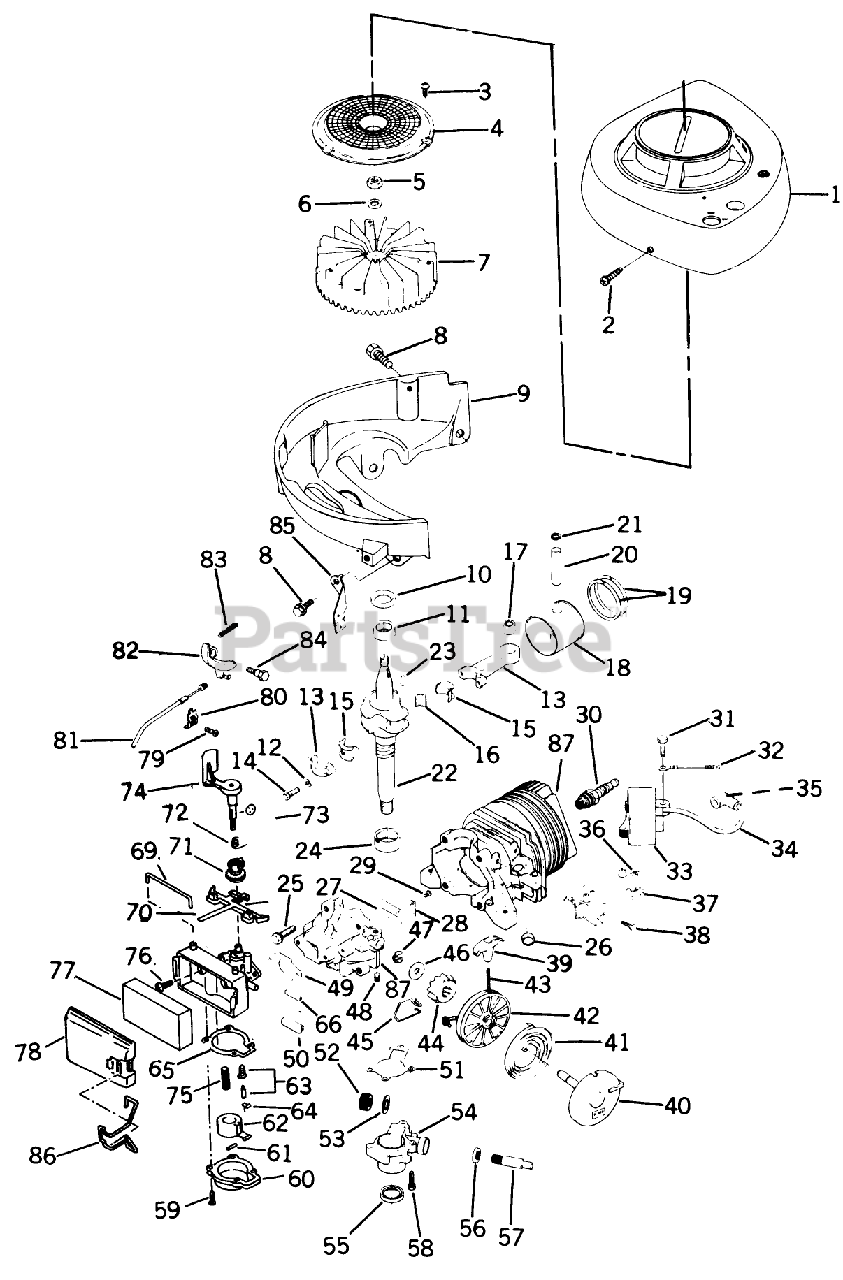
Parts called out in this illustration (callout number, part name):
2	SCREW F
3	SCREW F
5	NUT
8	SCREW-SEMS
11	BEARING V
14	SCREW
15	LINER ASM
17	BEARING AY F
21	RING-RETAINING
23	KEY
24	BEARING S
25	SCREW S
26	PLUG-CORE VF
28	PLATE-BACKUP, REED
34	HT LEAD&COVER XEV
36	NUT-CLIP
37	BRACKET S
39	HANDLE STARTER S
41	SPRING S
45	SPRING F
46	WASHER S
48	SET SCREW
49	GASKET CARB S
51	GASKET S
52	GEAR, DR SHAFT S
53	THRUST WASHER
56	SEAL S
59	SCREW-HH
66	TUBING PRIMER S
68	F-SCREW CARB
69	RETAINER
71	COLLAR-ADJUST, AIRVANE
72	SPRING-THRO. S
73	DISC S
74	AIR VANE&SHAFT S
76	SCREW
80	CLIP S
82	LEVER LOCKOUT S
84	BOLT S
86	RETAINER-COVER, FILTER
